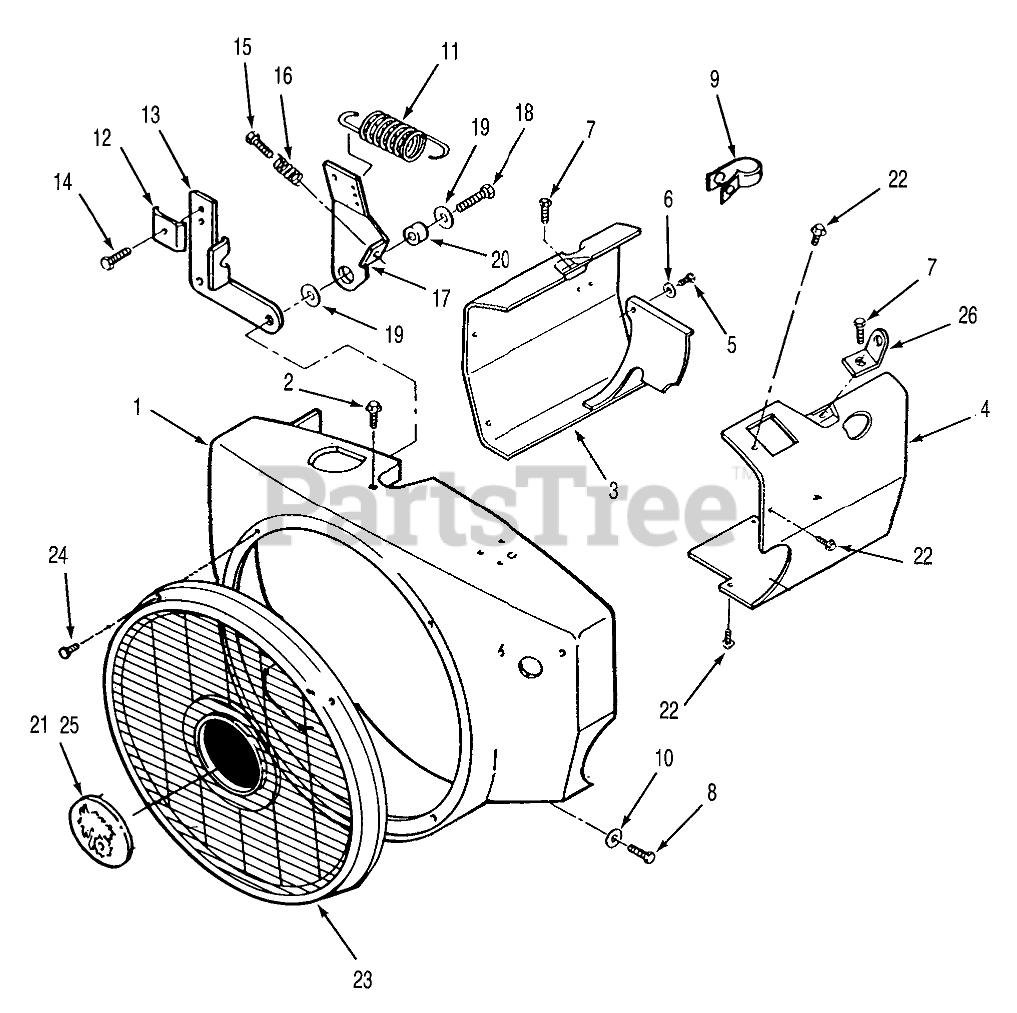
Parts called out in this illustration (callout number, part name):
1	Blower Housing
2	Bolt
3	CYLINDER AIR HSG L H
4	Cylinder Air Housing
5	Bolt
6	Screw
7	Bolt
8	Bolt
9	Clamp
10	Washer
11	Spring
12	Clip
13	Bracket
14	Bolt
15	Bolt
16	Spring
17	Governor Control Arm w/o Swivel
18	Bolt
19	Screw
20	Bushing
21	Plug
22	Bolt
23	Stationary Guard
24	Screw 1/4-20 x 3/8
25	NAME PLATE LOGO
26	Bracket-Lifting
